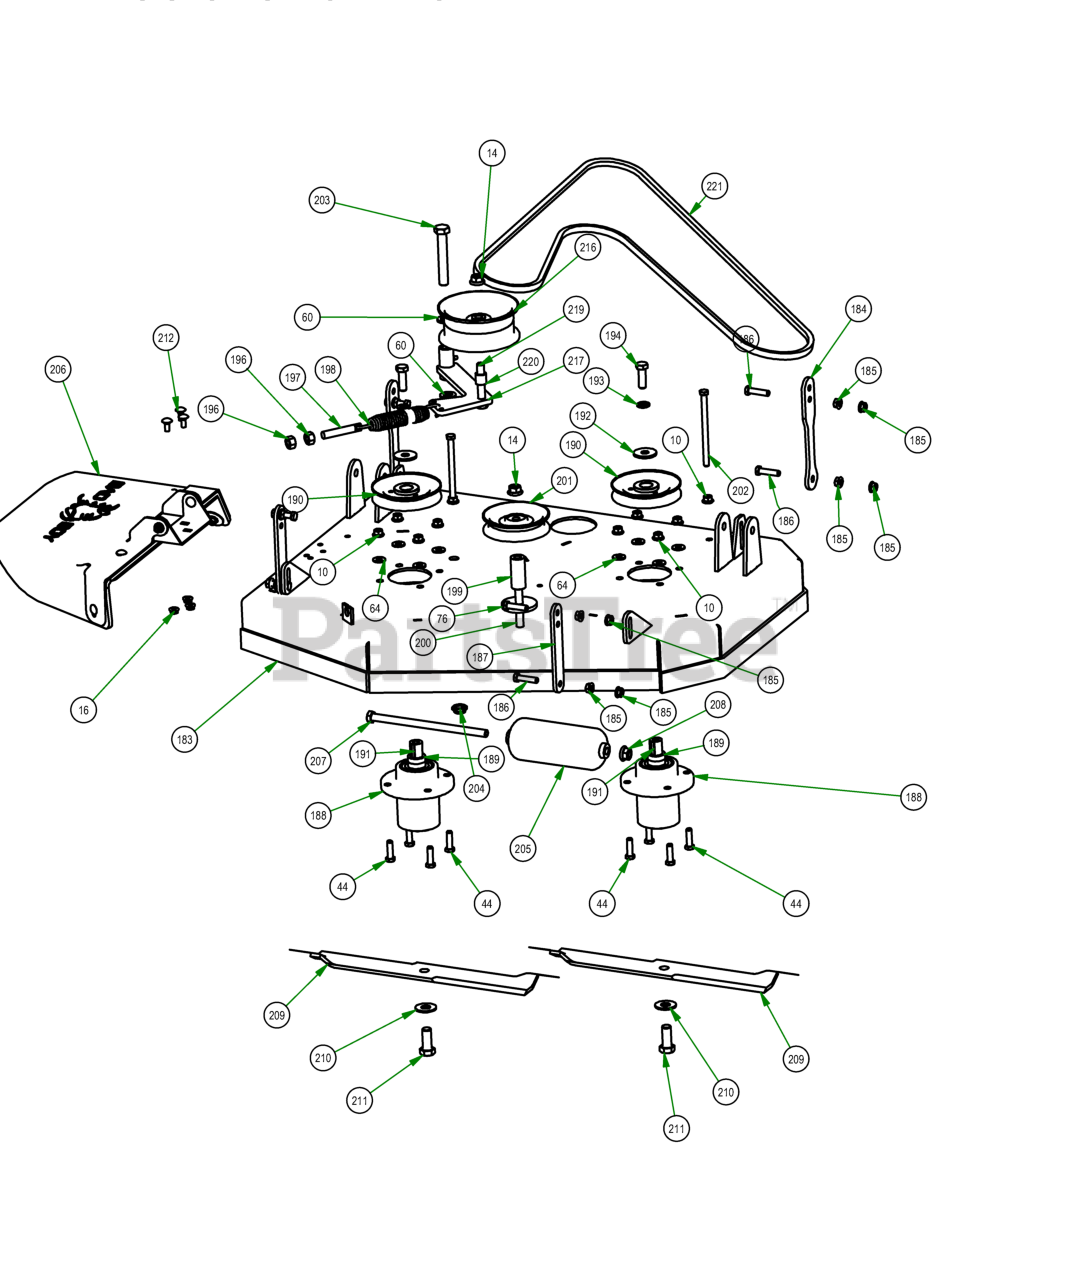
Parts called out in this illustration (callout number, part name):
10	3/8-16 Nylon Insert Flange Locknut
14	1/2-13 Nylon Insert Flange Locknut
16	5/16-18 HEX SERRATED FLANGE NUT HARD/ZINC
44	3/8-16 X 1-1/4 HEX CAP SCREW (GR.5) ZINC
60	.635 ID X 1.120 OD X .140 THICK FLAT WASHER NYLON
64	5/16 USS FLAT WASHER (7/8 OD) ZINC
76	MZ Deck Idler Spacer
183	2023 34 Stand On Deck Weldment
184	2019 Stand-On Rear Deck Hanger
185	3/8-16 HEX SERRATED FLANGE NUT HARD/ZINC
186	3/8-16 X 1-1/2 HEX CAP SCREW (GR.5) ZINC
187	2019 Revolt Front Deck Hanger
188	36'' Revolt Spindle Assembly
189	36 Deck Spindle Spacer
190	MZ Deck Pulley
191	3/16 X 1 SQ MACHINERY KEY 1018 STL ZINC
192	1/2 BELLEVILLE WASHER (1-5/8 OD X .140 THK) ZINC
193	1/2 SPLIT LOCKWASHER (GR.8) ZINC/YELLOW
194	1/2-20 X 1-1/2 HEX CAP SCREW (GR.5) ZINC
196	1/2-13 HEX NUT ZINC
197	All Thread
198	2009 Deck/Pump Idler Spring
199	2019 Revolt Stationary Idle Spacer
200	1/2-13 X 4-1/2 HEX CAP SCREW (GR.5) ZINC
201	5 V Idler Pulley 1/2" Bore
202	3/8-16 X 5-1/2 HEX CAP SCREW (GR.5) ZINC
203	5/8-11 X 4 HEX CAP SCREW (GR.8) ZINC YELLOW
204	5/8-11 NYLON INSERT JAM LOCKNUT ZINC
205	3in deck roller
206	MZ Discharge Chute Assembly
207	1/2-13 X 9 HEX CAP SCREW (GR.5) ZINC
208	1/2-13 HEX FLANGE AUTO OVAL LOCKNUT (GR.F) ZINC/WAX
209	34'' DeckBlade
210	5/8'' Flat Washer
211	5/8-18 X 1-1/2 HEX CAP SCREW (GR.8) ZINC YELLOW
212	5/16-18 x 3/4 Carriage Bolt
216	5 3/4" Deck Idler Pulley
217	2020 36 Deck Idler Arm Weldment
218	1/4-28 Grease Fitting
219	1/2-13 X 3 HEX CAP SCREW (GR.5) ZINC
220	.51 ID X .75 OD X .75 LGTH SOLID SPACER ZINC
221	34'' deck belt 94.25''
